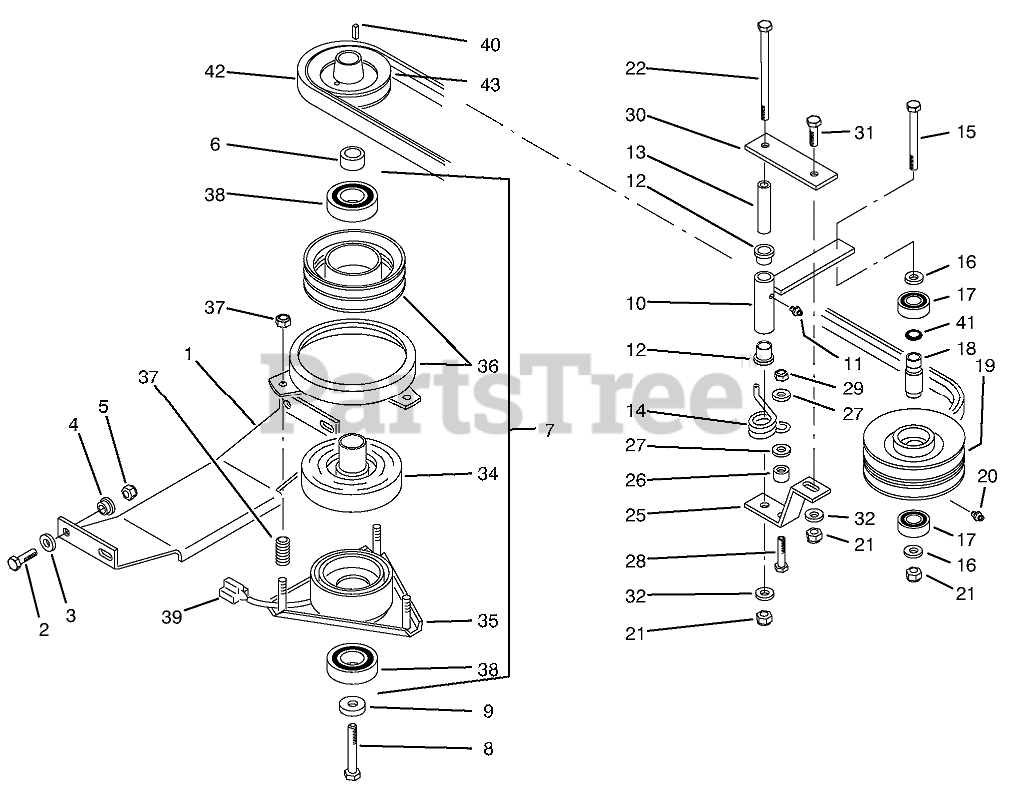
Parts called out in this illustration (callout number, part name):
1	BRACKET CLUTCH ST R
2	SCREW-HH
3	WASHER-PLAIN
4	BUSHING
5	NUT-LOCK, NI
6	SPACER
7	Electric Clutch Assembly (Incl. Ref. # 34-39)
8	SCREW-HH
9	WASHER
10	Arm-Idler
11	Fitting-Grease
12	BUSHING
13	SPACER
14	SPRING-TORSION
15	SCREW-HH
16	Washer
17	BEARING-BALL
18	SPACER-PTO IDLER
19	PULLEY 2- GROOVE
20	FITTING-GREASE
21	NUT-LOCK, NI
22	SCREW-HH
25	Bracket-Idler
26	Spacer
27	WASHER-FLAT
28	SCREW-HH
29	NUT-LOCK, NI
30	Plate
31	SCREW-HH
32	WASHER-FLAT
34	ROTOR ASSEMBLY
35	Field Assembly (Incl. Ref. #38 & 39)
36	Armature Assembly (Incl. Ref. #38)
37	ACCESS SPRING & NUT
38	BEARING-ELEC CLUTCH
39	CONNECTOR BODY B
41	O RING
42	V-BELT
43	PULLEY
